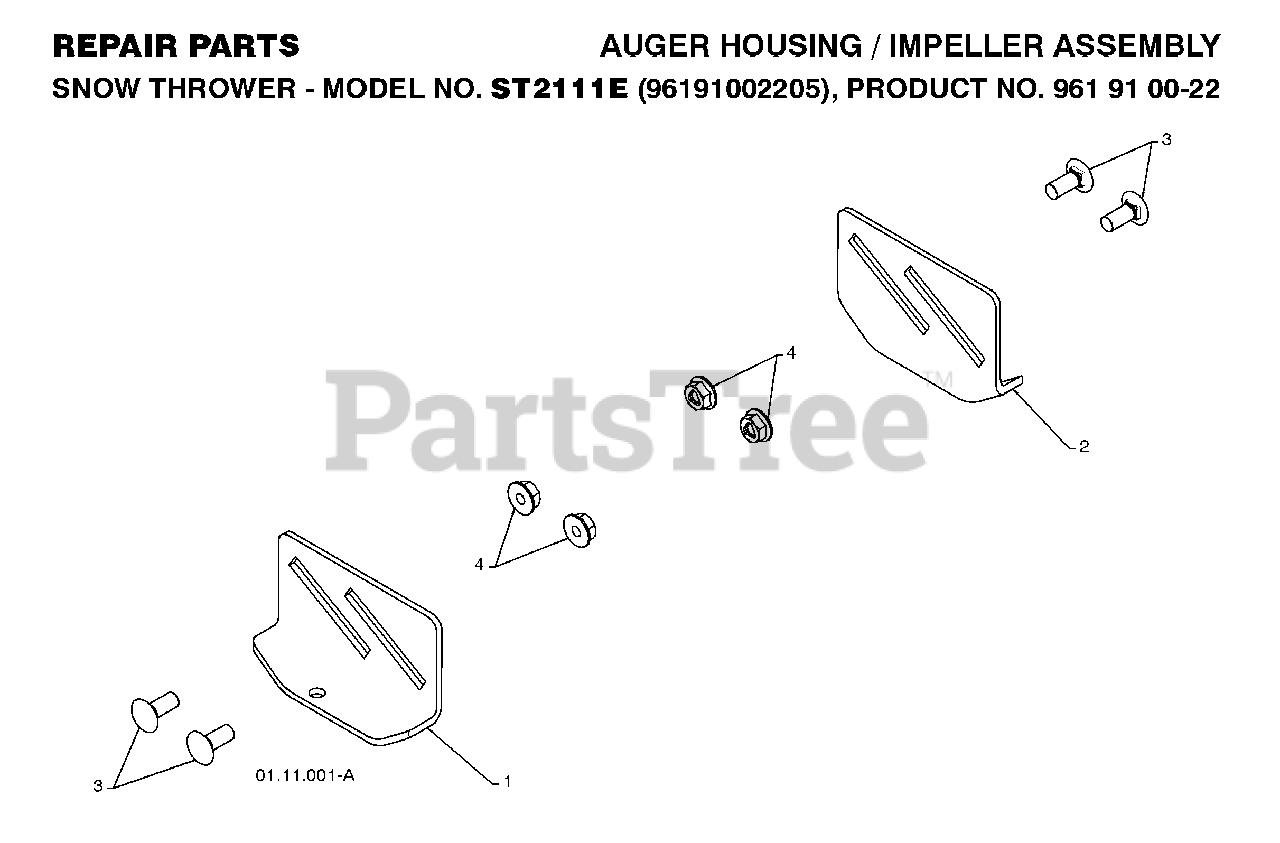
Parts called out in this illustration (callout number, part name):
1	SKID PLATE LH
2	SKID PLATE RH
4	NUT, LOCK 5/16-18
